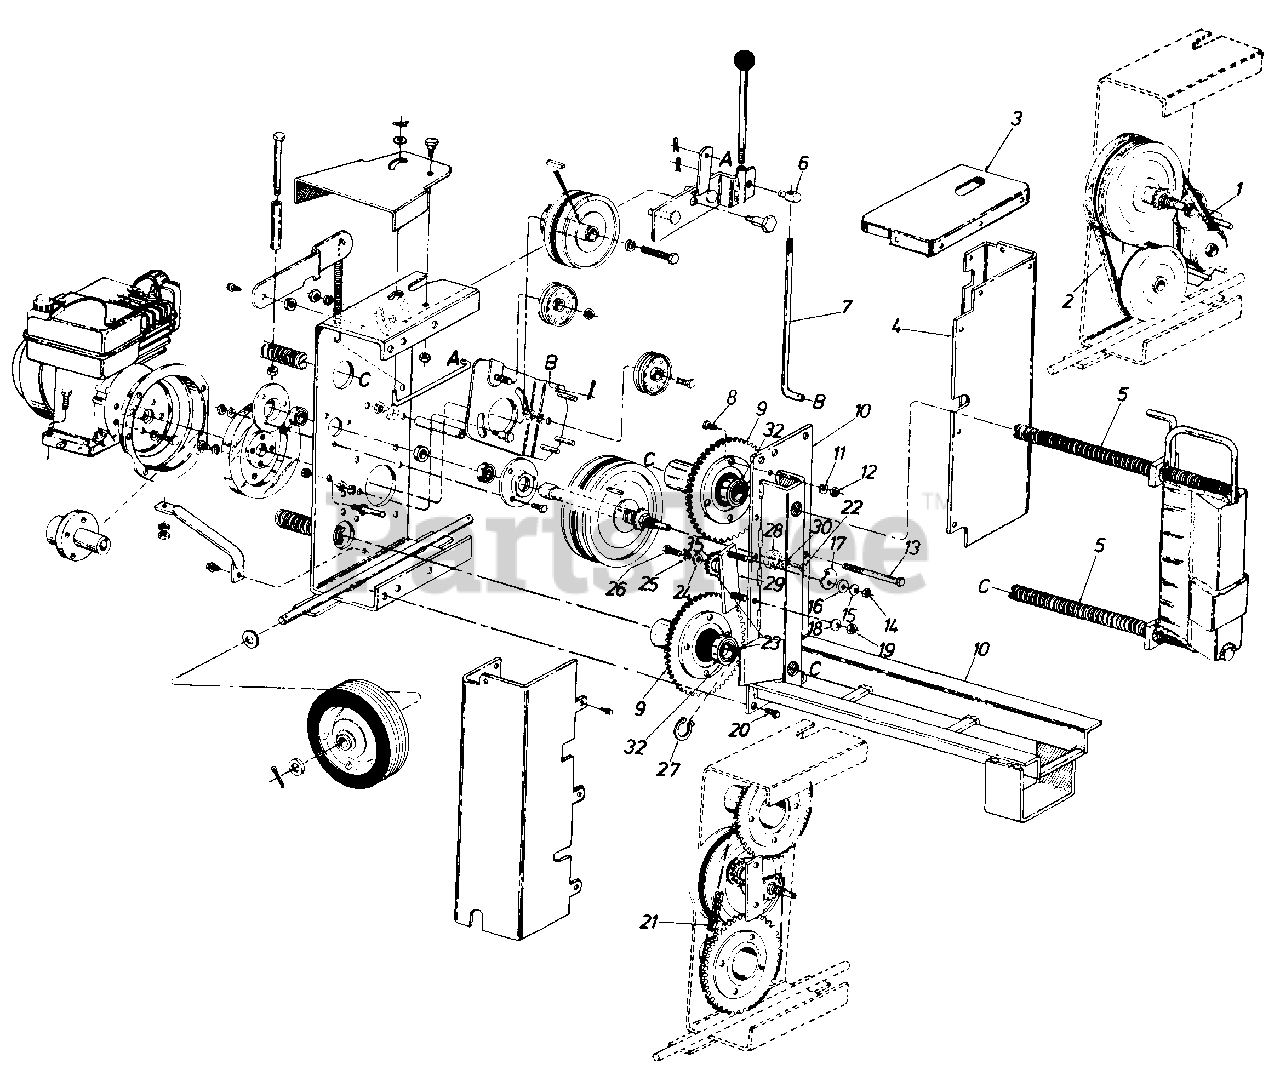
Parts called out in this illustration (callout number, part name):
1	V-Belt 1/2 x 40" Lg.
2	V-Belt 1/2 x 35 Lg.
3	End Cover
4	L.H. Belt Cover
5	Comp. Wedge & Screw Ass'y.
6	Adjustment Ferrule
7	Lever Rod
8	Hex Bolt 5/16-18 x 1.00" Lg.*
9	Sprocket Hub Ass'y.
10	Frame Weldment Ass'y.
11	L.-Wash 5/16" 1.D.*
12	Hex Nut 5/16-18 Thd.*
13	Hex Bolt 3/8-16 x 5.5" Lg.
14	Hex Nut 3/8-16 Thd.*
15	L.-Wash. 3/8" I.D.
16	Fl.-Wash. 3/8 I.D. x 1.0 O.D. x 13
17	Chain Adjuster
18	Bell Wash. 3/8" I.D.
19	Hex Nut 3/8-16 Thd. *
20	Hex Wash. SF Tapp Scr. 3/8 x 7/8" Lg.
21	131 Link Chain #420
22	Hex Scr. 1/4-28 x .62" Lg.
23	10 Tooth Sprocket Ass'y.
24	Fl.-Wash. 3/8 I.D. x 1.25 O.D. x 10 Thd.
25	L.-Wash . 3/8" I.D. *
26	Hex BoIt 3/8-24 x 1.0" Lg.*
27	Snap Ring 45mm.
28	Ball Bearing .50 I.D. x 1.38 O.D. x .437
29	Idler Bracket Ass'y. Comp.
30	Fl.-Wash. 1/4 I.D. x 3/4 O.D. x.063
32	Ball Bearing
35	Spacer.380" I.D. x .625" O.D. x 1.0" Lg.
